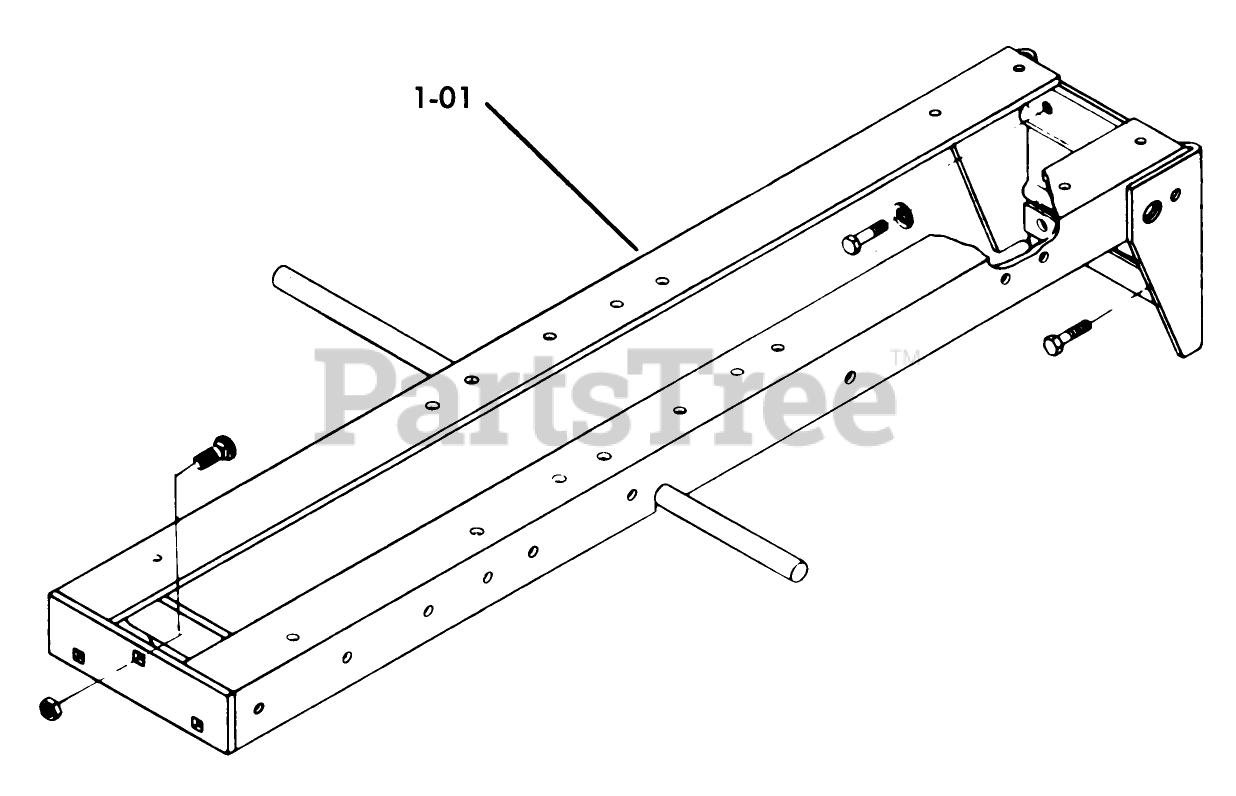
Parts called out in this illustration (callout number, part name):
1-01	Assy-Frame
1-01	Bolt
1-01	LOCKWASHER
1-01	Nut
